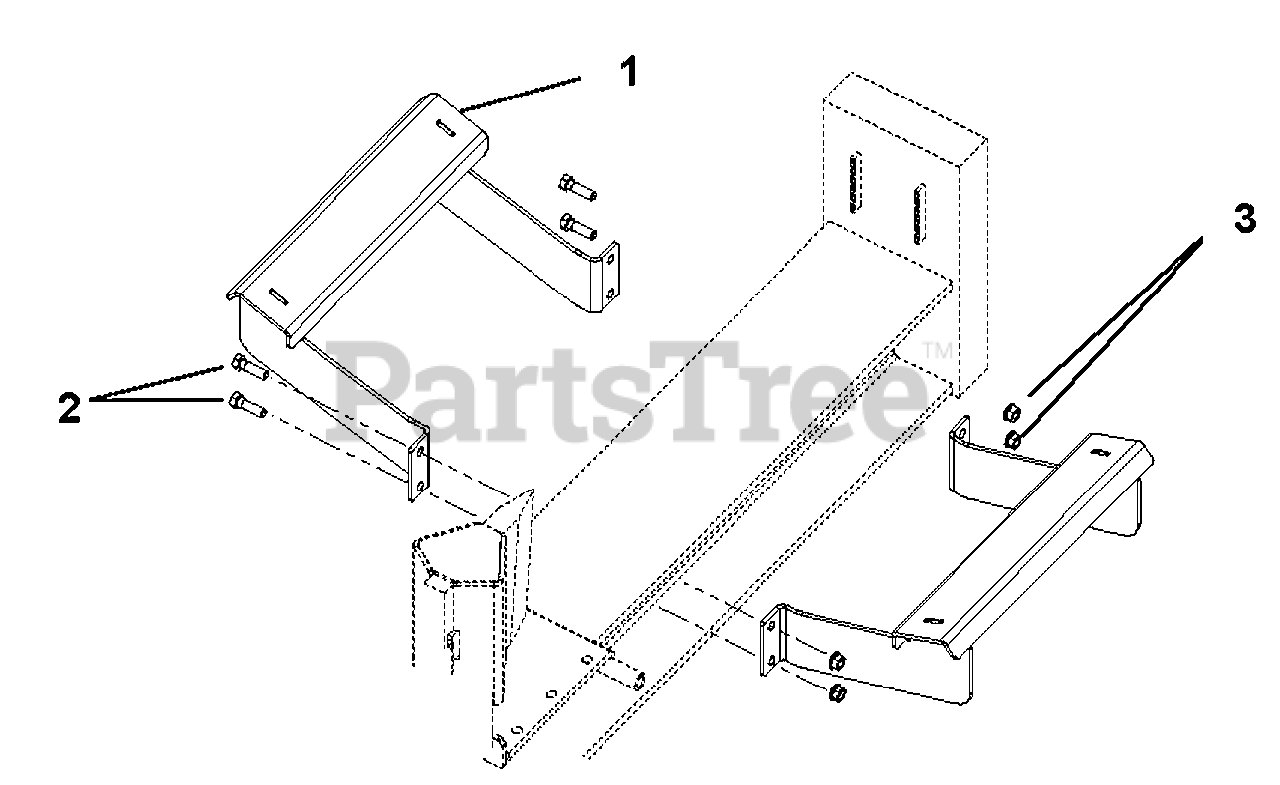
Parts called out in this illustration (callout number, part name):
1	Cradle, Log
2	Bolt, Hex .38-16 x 1.25
3	Nut, Locking Top Flange .38-16
